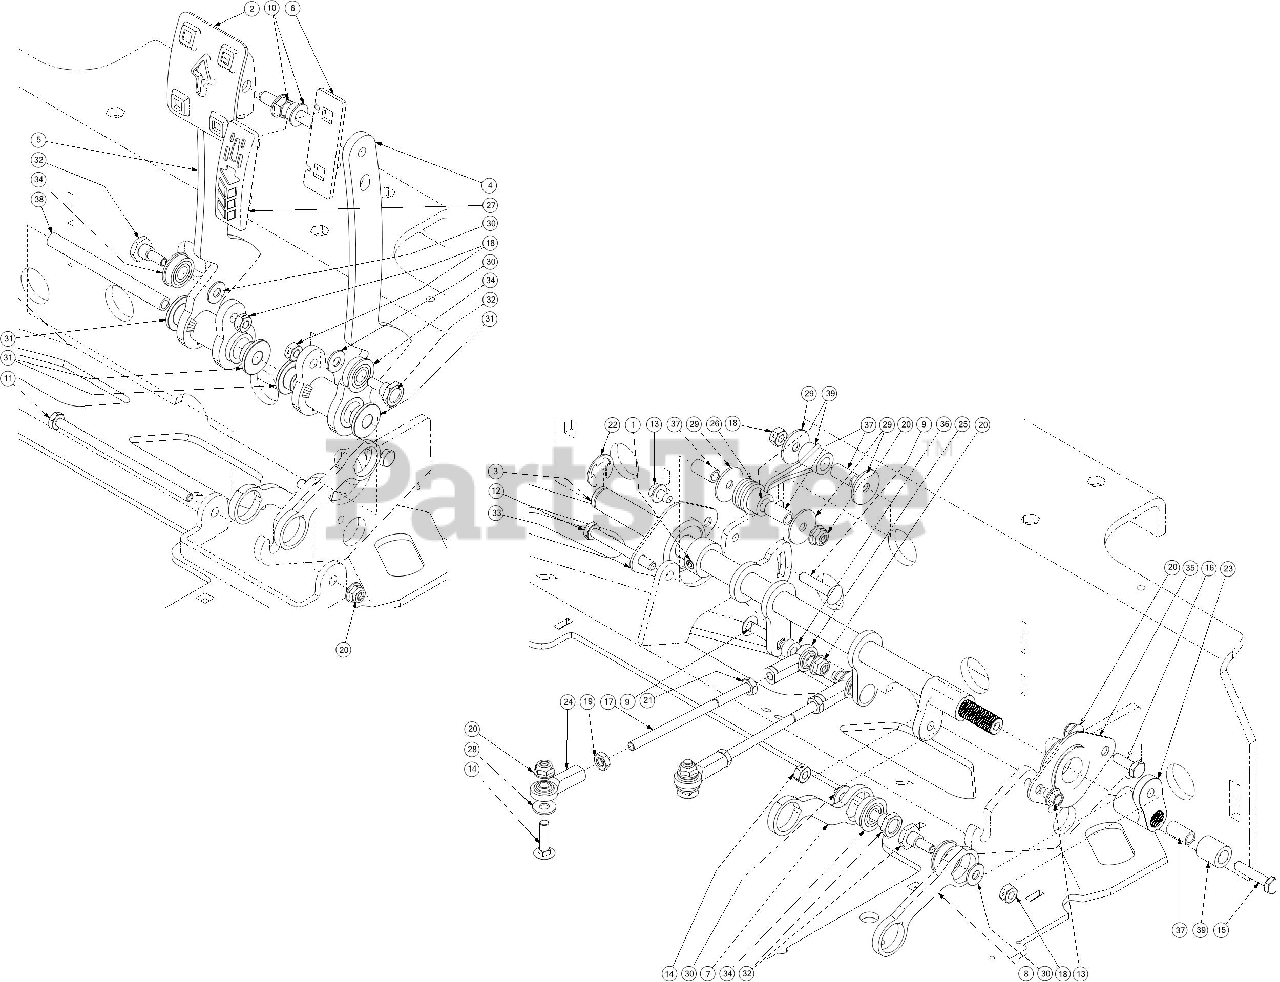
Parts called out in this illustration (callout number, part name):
1	SHAFT COLLAR .625
2	FORWARD PEDAL
3	SPEED CONTROL ARM ASSEMBLY
4	REVERSE PEDAL ASSEMBLY
5	FORWARD PEDAL ASSEMBLY
6	REVERSE PEDAL BRACKET
7	FORWARD PEDAL LINK
8	REVERSE PEDAL LINK
9	CARRIAGE BOLT 1/4-20 X 1.25 G
10	SCREW 5/16-18 X .750
11	SCREW 1/4-20 X 5.00 GR5
12	SCREW 1/4-20 X 2.25 GR5
13	SCREW 1/4-20 X .375
14	SCREW 1/4-20 X 1 GR5
15	SCREW 1/4-20 X 1.25 GR5
16	SCREW 1/4-20X.75 GR5
17	SPEED CONTROL ROD
18	HEX NUT
19	HEX JAM NUT 1/4-28
20	FLANGE LOCK NUT
24	END ROD (RH)
26	TORSION SPRING
27	REVERSE PEDAL PAD
28	FLAT WASHER
29	FLAT WASHER
30	FLAT WASHER .271:.630:.065
31	SHOULDER SPACER
32	SHOULDER SCREW .37
33	BALL BEARING
34	FLANGE BEARING
35	BALL BEARING
37	SPACER .260 X .375 X .75
39	SPACER-.375X.625X.600
